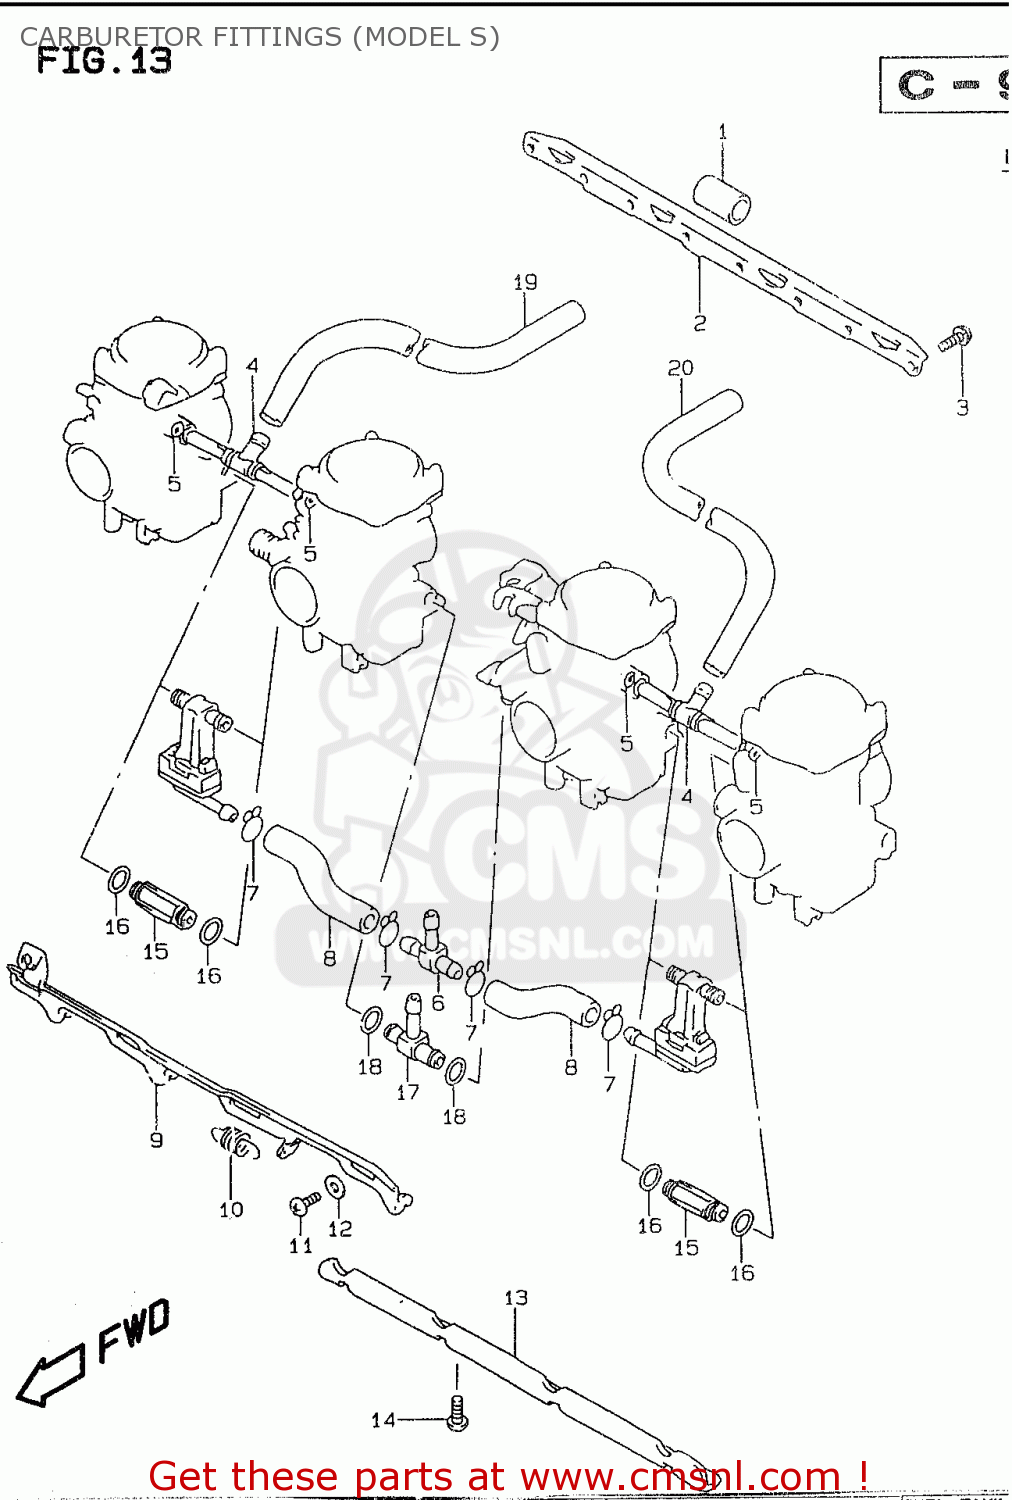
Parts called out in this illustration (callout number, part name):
1	PIPE
2	STAY,PLATE
3	SCREW
4	JOINT
5	O RING
6	JOINT
7	CLAMP
8	HOSE
9	LEVER,STARTER
10	SPRING
11	SCREW
12	WASHER
13	STAY,PLATE
14	SCREW
15	JOINT
16	O RING
17	JOINT
18	O RING
19	HOSE(7X11X600)
20	HOSE(7X11X600)
